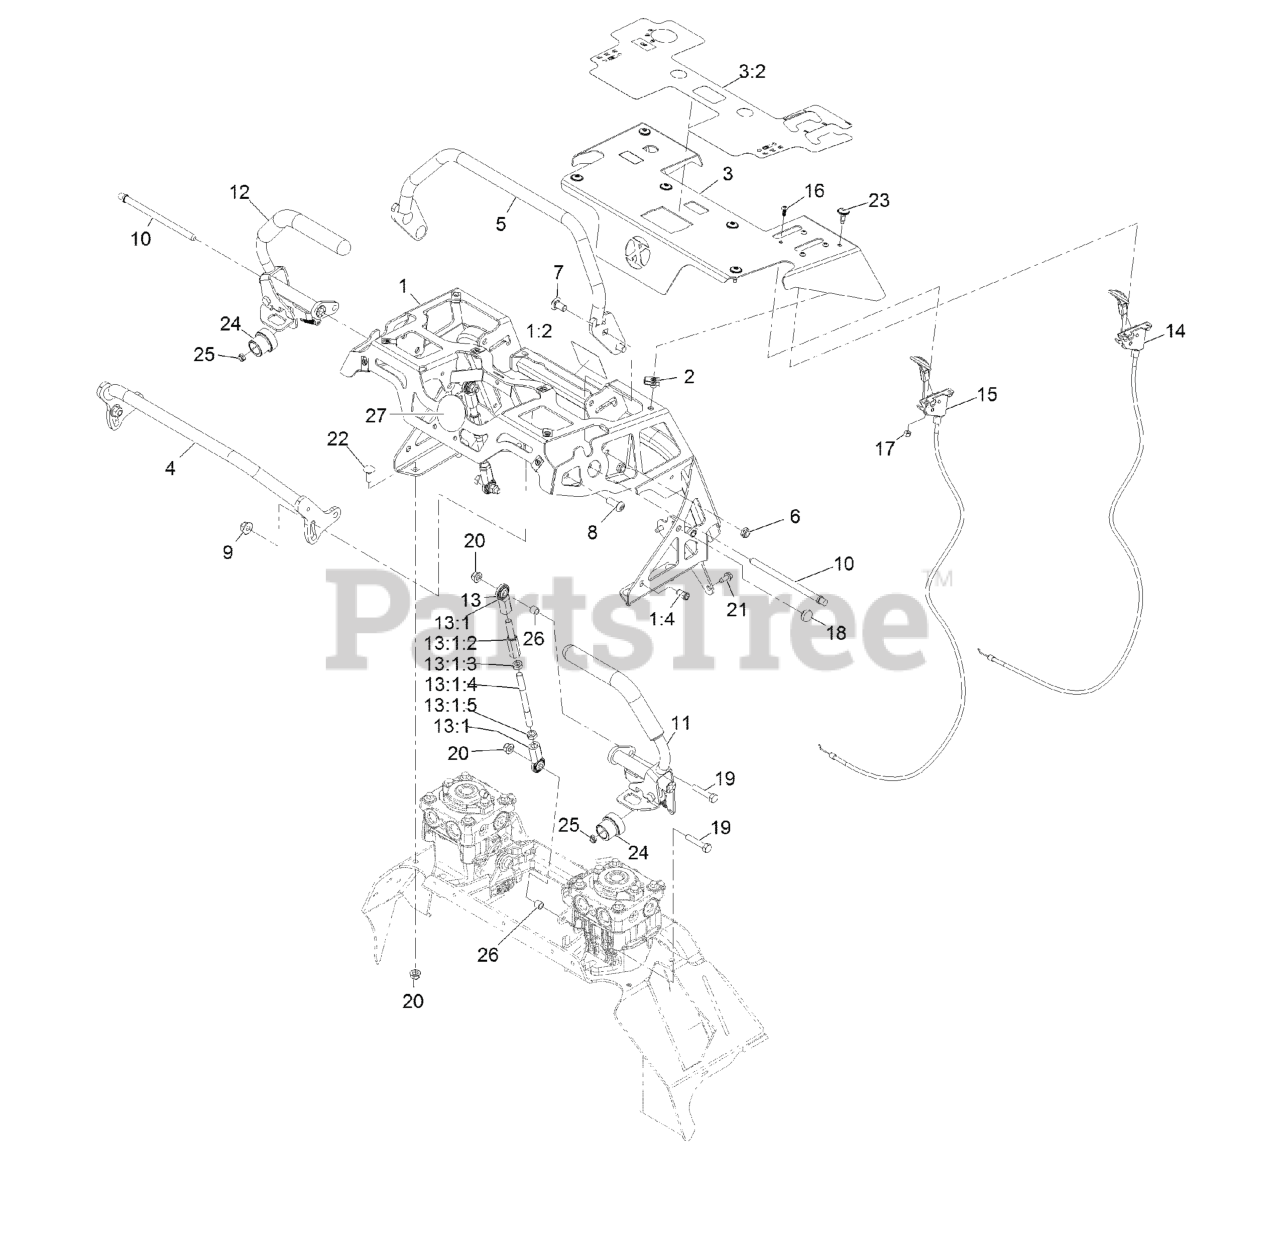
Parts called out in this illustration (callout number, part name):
1	ASM-CTRL TOWER
1:2	DECAL-HYD FLUID WARN
1:4	NUT-CLINCH,HEX
3	ASM, CONTROL PANEL W/ DECALS
3:2	DECAL-CONTROL PANEL NON-EFI
4	WELD, FRONT REF BAR
5	WELD, REAR REF BAR
7	SCREW-CARR
8	SCREW-HSBH
9	NUT-HF, NI
10	PIN, PIVOT
11	ASM, MOTION CONTROL, LT
12	ASM, MOTION CONTROL, RT
13	ASM, LINKAGE
13:1	ASM, Motion Control Link
13:1:2	ROD-ADJUSTMENT
13:1:3	NUT-HEX JAM, LH
13:1:5	NUT-HJ
14	CONTROL, CHOKE
15	CONTROL, THROTTLE
16	SCREW, BHCS
17	NUT-LOCK, NI
19	SCREW-HH
20	NUT-HF, NI
21	SCREW-HWH
22	SCREW-CARR
23	SCREW, TORX
25	NUT-LOCK, NI
27	DECAL-COVER
